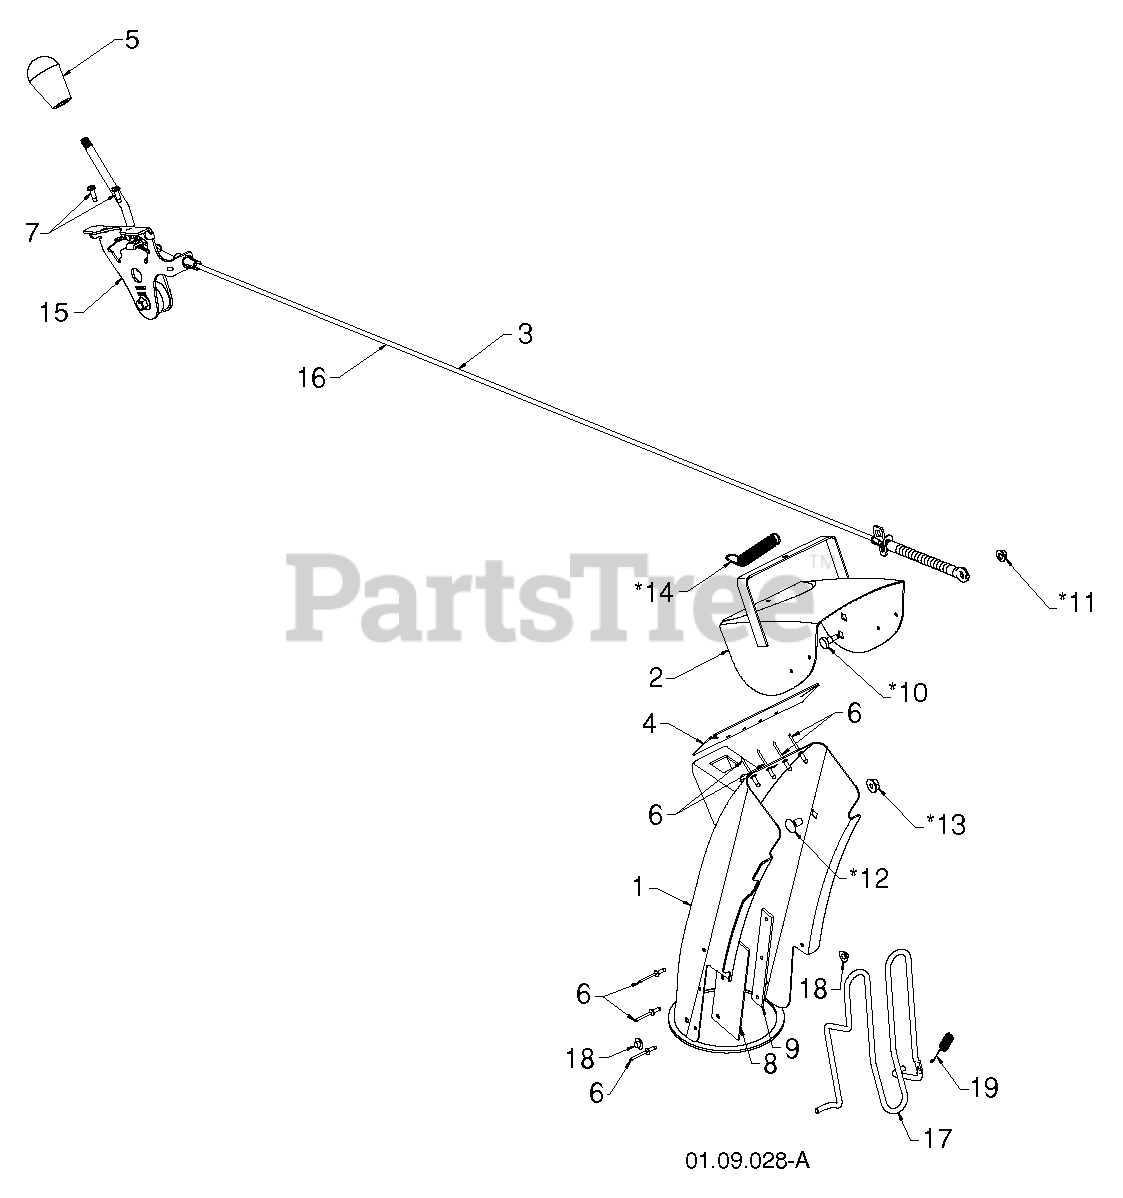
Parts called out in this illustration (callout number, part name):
1	RP_CHUTE.WELDMENT.SNOW.ORANGE
2	DEFLECTOR.WELDMENT.PNT.ORANGE
3	RP CRTL.ASM.DEFLECTOR.BLACK.SN
4	SEAL.DEFLECTOR
5	KNOB.OVERMOLD.DS.HUSQVARNA/BLK
6	RIVET BLIND
8	SHIELD.SNOW.CHUTE
9	STRAP.SHEILD.RETAINER
10	BOLT, SHOULDER
11	NUT.HEX.FLANGE.1/4
12	BOLT
13	NUT.LOCK.5/16-18
14	SPRING.DEFLECTOR.REM.CHUTE
15	RP CNTRL.HEAD.ASSEM.DEFLECTOR
16	CABLE.DEFLECTOR.SNOW
17	ROD.GUARD.CHUTE (2 2)
18	NUT
19	SPRING.CHUTE.GUARD
